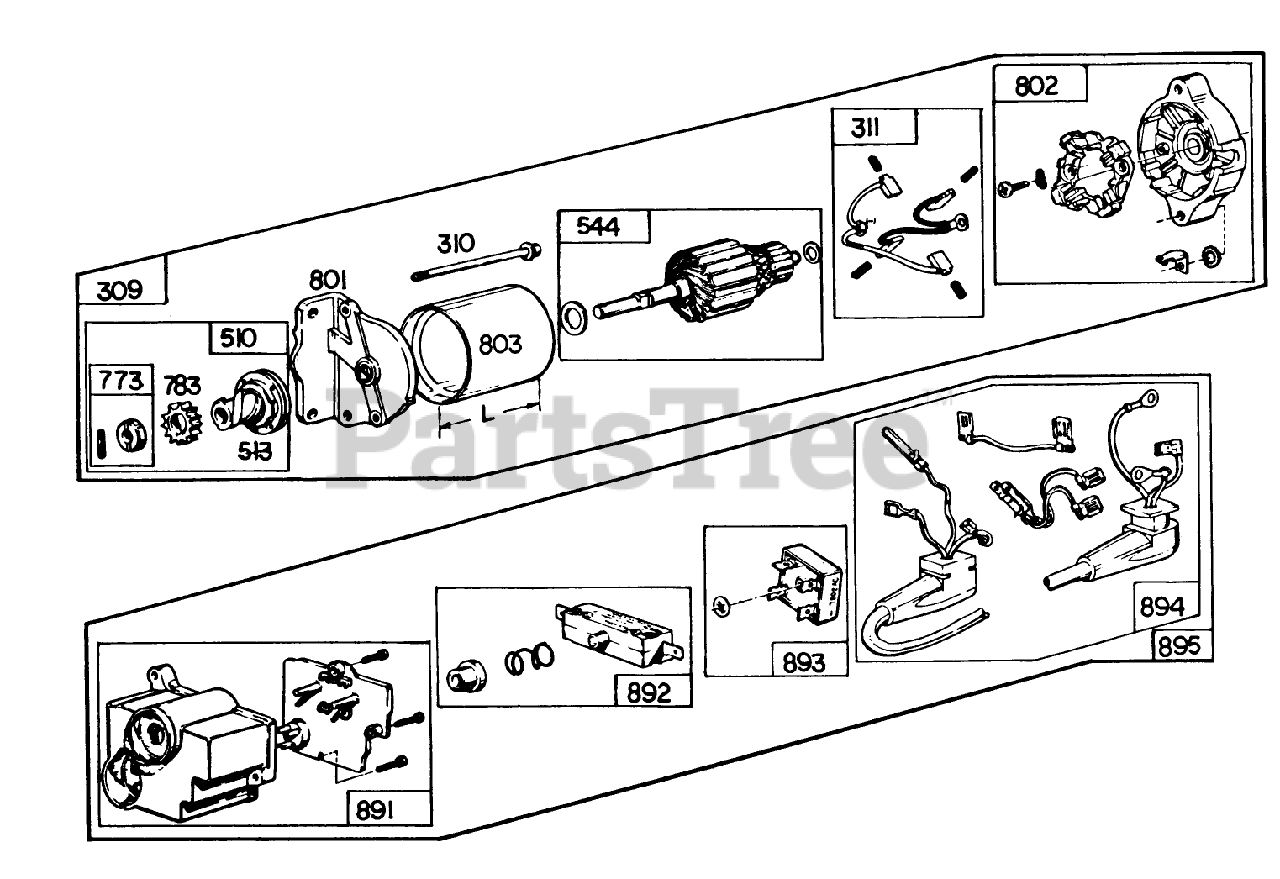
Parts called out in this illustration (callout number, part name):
309	Motor Drive Assembly
310	Thru Bolt Assembly
311	Brush Assembly
510	Drive Assembly
513	Clutch Assembly
544	Armature Assembly
773	Gear-Starter
801	Drive End Cap Assembly
802	Comm. End Cap Assembly
803	Housing Assembly
891	Housing Group
892	Switch Group
893	Rectifier
894	Lead Group
895	Control Group
